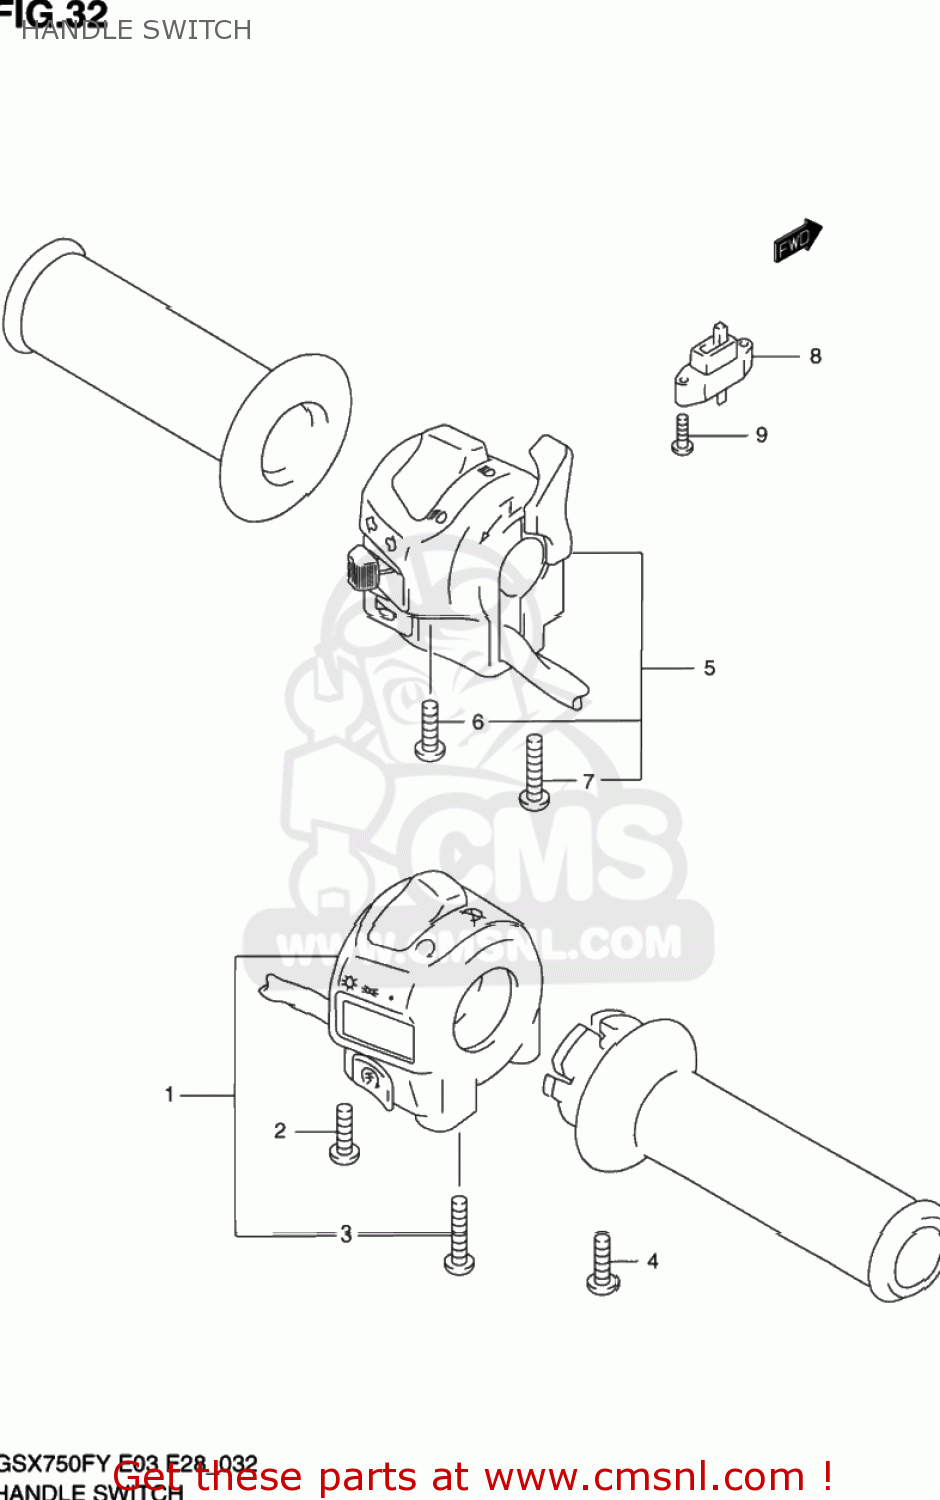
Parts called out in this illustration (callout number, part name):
1	SWITCH ASSY,HANDLE,R
2	SCREW
3	SCREW
4	SCREW
5	SWITCH ASSY,HANDLE,L
6	SCREW
7	SCREW
8	SWITCH ASSY,CLUTCH
9	SCREW
